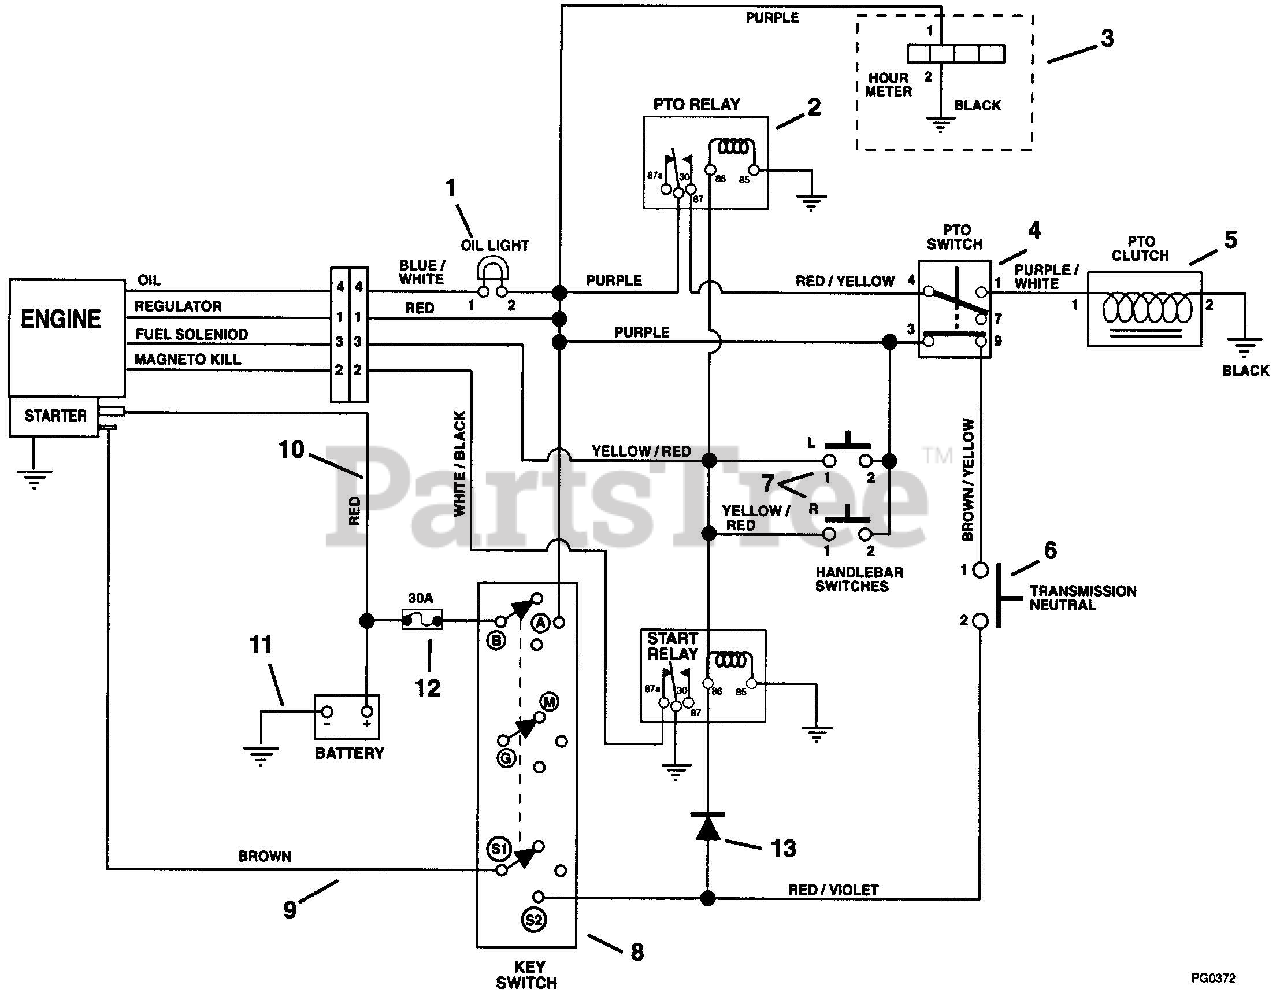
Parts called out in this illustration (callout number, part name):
1	Light - Indicator
2	Relay
3	Hour Meter
4	Switch - Clutch with Retainer
5	Clutch - Electric
7	Switch - Interlock
8	Key Switch
9	Cable - Starter
10	Cable - Battery to Starter
11	Cable - Negative Battery
12	Fuse 30 AMP
